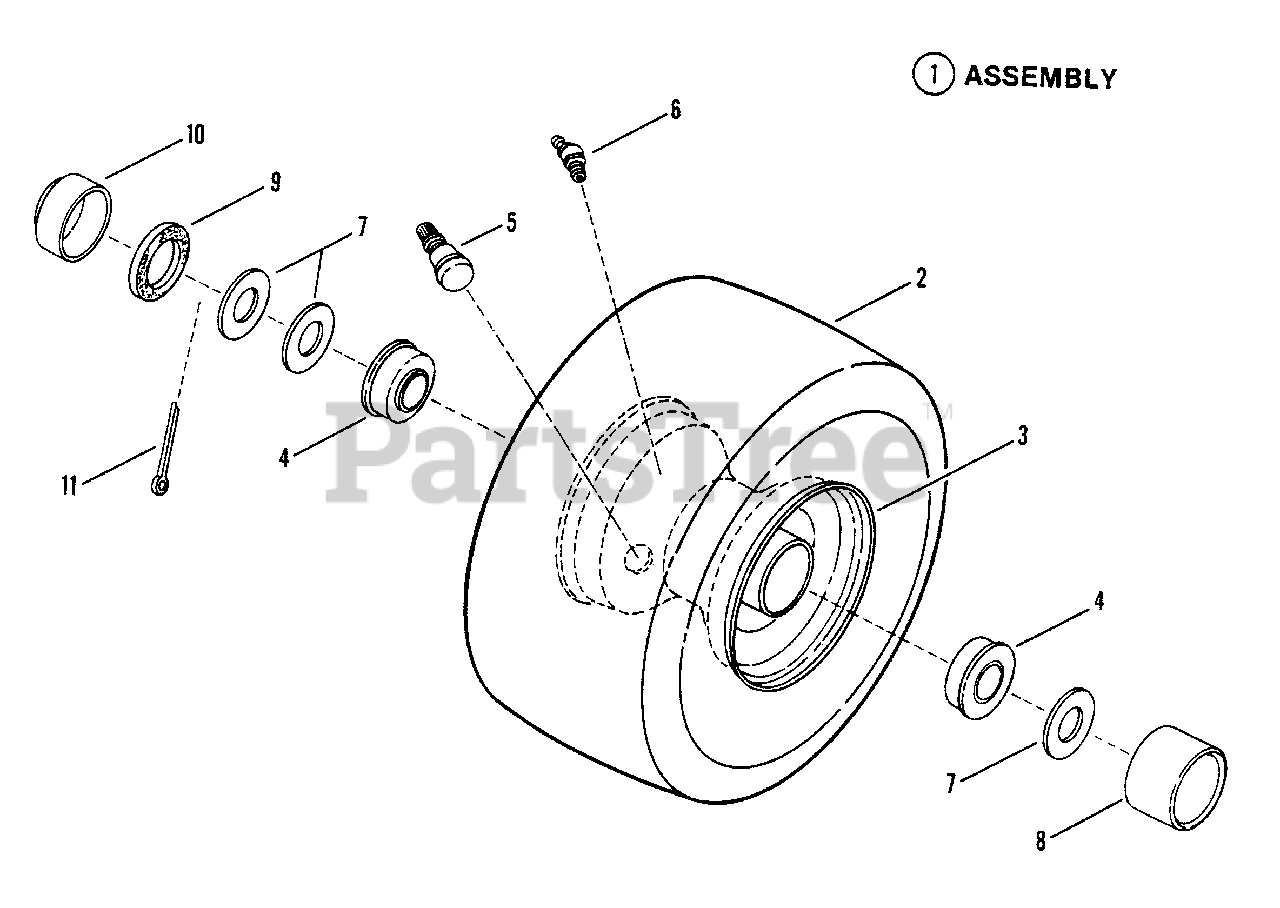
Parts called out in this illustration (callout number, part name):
1	ASSEMBLY, Front Tire & Rim (Complete) Stud
2	TIRE, 4.10/3.50 x 4
3	RIM
4	BEARING, Ball
5	VALVE, Air (Snap-in)
6	FITTING Lube
7	WASHER
8	CAP, Hub
9	SEAL, Felt
10	CAP, Dust
11	PIN, 5/32 x 1" Cotter
